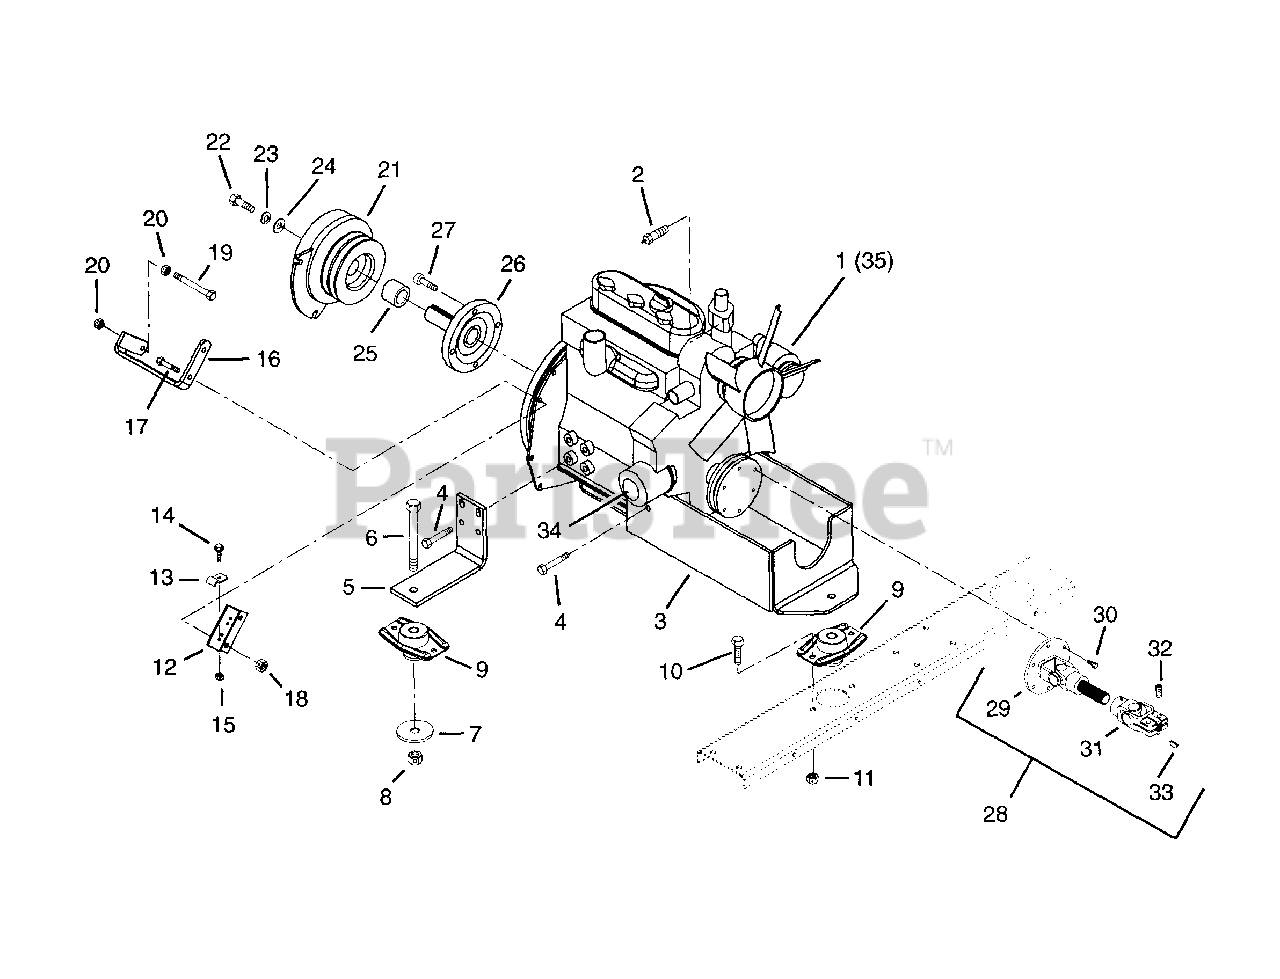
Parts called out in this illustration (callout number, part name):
1	Engine, Yanmar
2	Temperature Sender
3	Weldment, Front Engine Mount
4	Bolt-Hex M10-1.5 x 20 mm Grade 5
5	Bracket, Engine Mount
6	Bolt-Hex .50-13 x 2.75 Grade 5
7	Washer-Snub-Steel .53 x 2.38 x .125
8	Nut-Locking-Center .50-13
9	Mount, Engine Isolator
10	Bolt-Hex .38-16 x 1.00 Grade 5
11	Nut-Locking-Center .38-16
12	Bracket, Control
14	Screw-Machine 10-24 x .75 Hex Washer Head
15	Nut-Locking-Nylon 10-24 with Insert
16	Bracket, Clutch Stop
17	Bolt-Hex M8 x 1.25 x 25mm
18	Nut-Locking-Center M8 x 1.25
19	Bolt-Hex .31-18 x 2.50 Grade 5
20	Nut-Locking-Center .31-18
21	Electric Clutch
22	Bolt-Hex .375-24 x 1.25 Grade 5
23	Washer-Locking .38 x .094
24	Washer Retaining .406 x 1.625 x .25
26	Weldment, Clutch Stub Shaft
27	Screw-Socket Head M10 x 1.5 x 20mm
28	Driveline, Universal
29	Adapter, Flywheel
30	Bolt-Hex M8 x 1.25 x 16mm
31	Assembly, U-Joint
32	Screw-Set .38-16 x .50
33	Key-Woodruff .188 x .75 x .313
34	Oil Filter
35	Glow Plug
